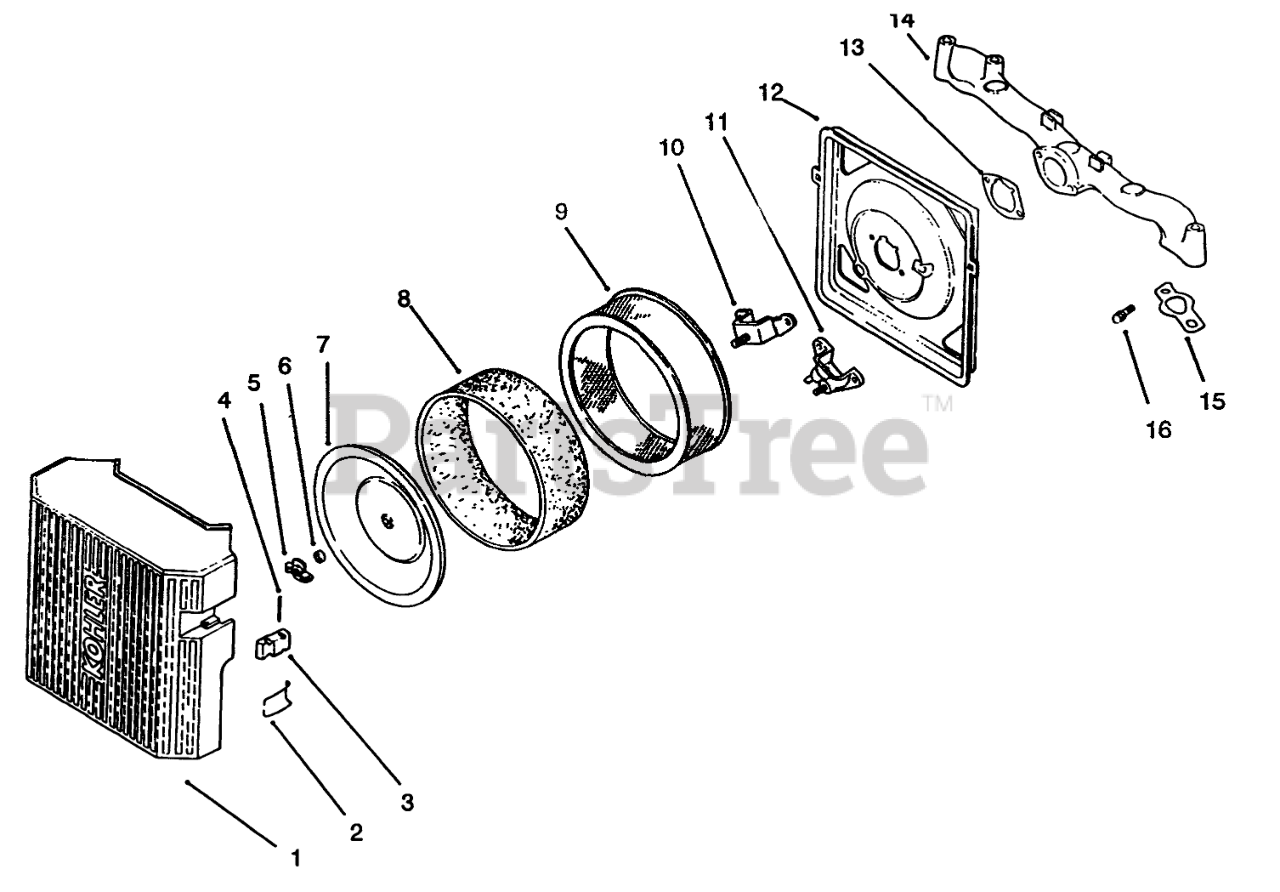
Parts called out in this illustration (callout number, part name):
1	Kit-A/C Cover INC 2-4 (Only On: 72103, 72083)
2	Spring-Latch (Only On: 72103, 72083)
3	Latch-Lever (Only On: 72103, 72083)
4	Pin-Latch Lever (Only On: 72103, 72083)
5	Nut-Wing (Only On: 72103, 72083)
6	Seal-Air Intake (Only On: 72103, 72083)
7	Cover-Inner Air Cleaner (Only On: 72103, 72083)
8	Element-Precleaner (Only On: 72103, 72083)
9	Element-Air Cleaner (Only On: 72103, 72083)
10	Cup-Fuel Spitback (Only On: 72103, 72083)
11	Gasket-Fuel Spitback Cup (Only On: 72103, 72083)
12	Base-Air Cleaner (Only On: 72103, 72083)
13	Gasket-A/C Base (Only On: 72103, 72083)
14	Manifold-Intake (Only On: 72103, 72083)
15	Gasket-Intake Manifold (Only On: 72103, 72083)
16	Screw M6x1.0x18 (Only On: 72103, 72083)
